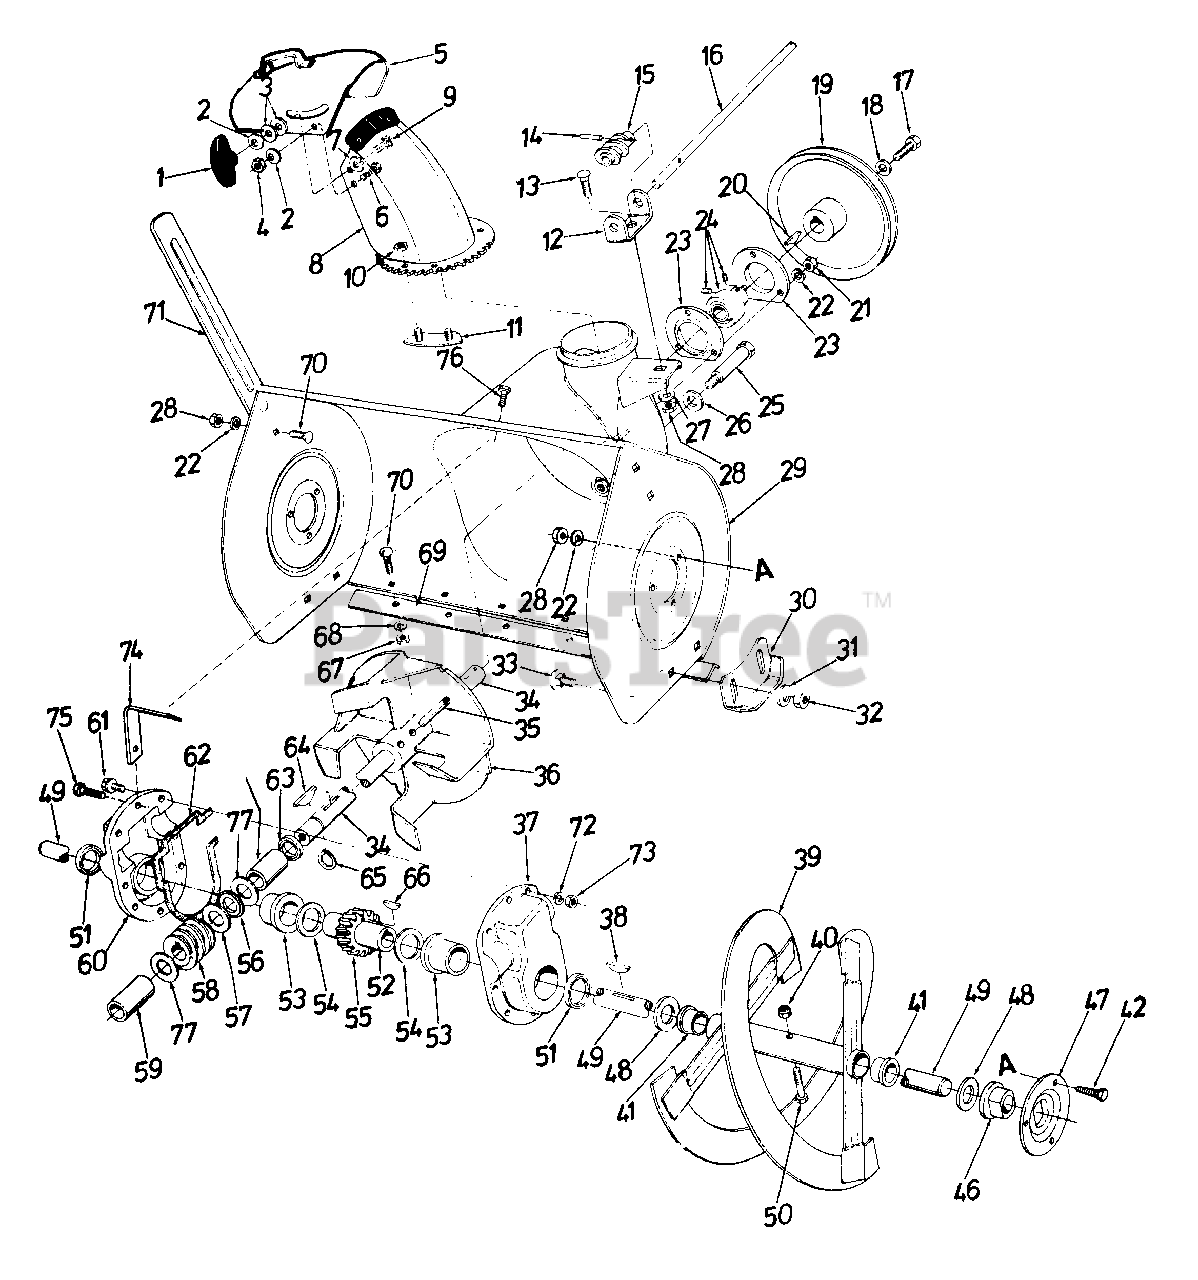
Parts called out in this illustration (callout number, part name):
1	Hand Knob Ass'y.
2	Bell-Wash. .345 I.D. x .88 O.D. x .060
3	Fl-Wash. .312 I.D. x 1.125 O.D. x .125
4	Hex Cent. L-Nut 5/16-18 Thd.
5	Top Chute Ass'y.
6	Carr. Bolt 5/16-18 x .62" Lg.
7	Fl-Wash. .53 I.D. x 1.25 O.D. x .100
8	Chute Ass'y.
9	Carr. Bolt 5/16-18 x 1.00" Lg.
10	Hex Cent. L-Nut 1/2-20 Thd.
11	Chute Flange Keeper Ass'y.
12	Chute Brkt.
13	Carr. Bolt 5/16-18 x .62" Lg.
14	Spring Pin Roll 1/8" Dia. x .75" Lg.
15	Worm - R.H. w/Three Threads
16	Chute Crank .38" Dia. x 41.0" Lg.
17	Hex L-Scr. 5/16-18 x .88" Lg.
18	Bell-Wash. .345 I.D. x .88 O.D. x .060
19	V-Pulley .875 I.D. x 10.12 O.D.
20	#9 Hi-Pro Key 3/16 x 3/4" Dia.
21	Hex Nut 5/16-18 Thd.
22	L-Wash. 5/16" Scr.
23	Bearing Hsg. - Self Aligning Brg.
24	Self Aligning Brg. .875 I.D.
25	Stud 3/8-16 x 2.75" Lg.
26	Bell-Wash. .400 I.D. x .88 O.D. x .060
27	Bell-Wash. .345 I.D. x .88 O.D. x .060
28	Hex Nut 5/16-18 Thd.
29	Blower Hsg. Ass'y.
30	Slide Shoe
31	Bell-Wash. .400 I.D. x .88 O.D. x .060
32	Hex Nut 3/8-16 Thd.
33	Carr. Bolt 3/8-16 x .75" Lg.
34	Blower Axle
35	Spring Pin Spiral 5/16" Dia. x 1.75" Lg.
38	#91 Woodruff Key 1/4" x 3/4" Dia.
41	Plastic Bushing
42	Hex Sems Scr. 5/16-18 x .75" Lg.
46	Flange Brg. w/Flats 1.00" I.D.
47	Bearing Hsg. - Spiral Hsg.
48	Fl-Wash. 1.06 I.D. x 1.75" O.D. x .100
49	Spiral Axle - 26"
50	Hex Scr. 5/16-18 x 1.75" Lg.
51	Oil Seal 1.50" I.D.
52	Worm Gear Shaft
53	Flange Brg. 1.503 I.D.
54	Fl-Wash. 1.50 I.D. x 2.00 O.D. x .030
55	Double Threaded Worm Gear
56	Thrust Brg. .88 I.D. x 1.44 O.D. x .078
57	Fl-Wash. .88 I.D. x 1.40 O.D. x .150
58	Double Threaded Worm - L.H.
59	Sleeve Brg. .875 I.D.
60	Complete Gear Hsg. Half - R.H.
61	Hex Scr. 5/16-18 x 1.00" Lg.
62	Gasket
63	Oil Seal .875" I.D.
64	#9 Hi-Pro Key 3/16 x 3/4" Dia.
65	Snap Ring for .875" Dia. Shaft
66	#91 Woodruff Key 1/4 x 3/4" Dia.
67	Hex Nut 5/16-18 Thd.
68	L-Wash. 5/16" Scr.
70	Carr. Bolt 5/16-18 x .62" Lg.
71	Drift Cutter
72	Wave Wash. 5/16" Scr.
73	Hex Ins. L-Nut 5/16-18 Thd.
74	Gear Hsg. Support Brkt.
75	Hex Scr. 5/16-18 x 1.25" Lg.
76	Hex Wash. Hd. Self-Tap Scr. 5/16-24 x .50" Lg.
77	Fl-Wash..88 I.D. x 1.40 O.D. x .150
